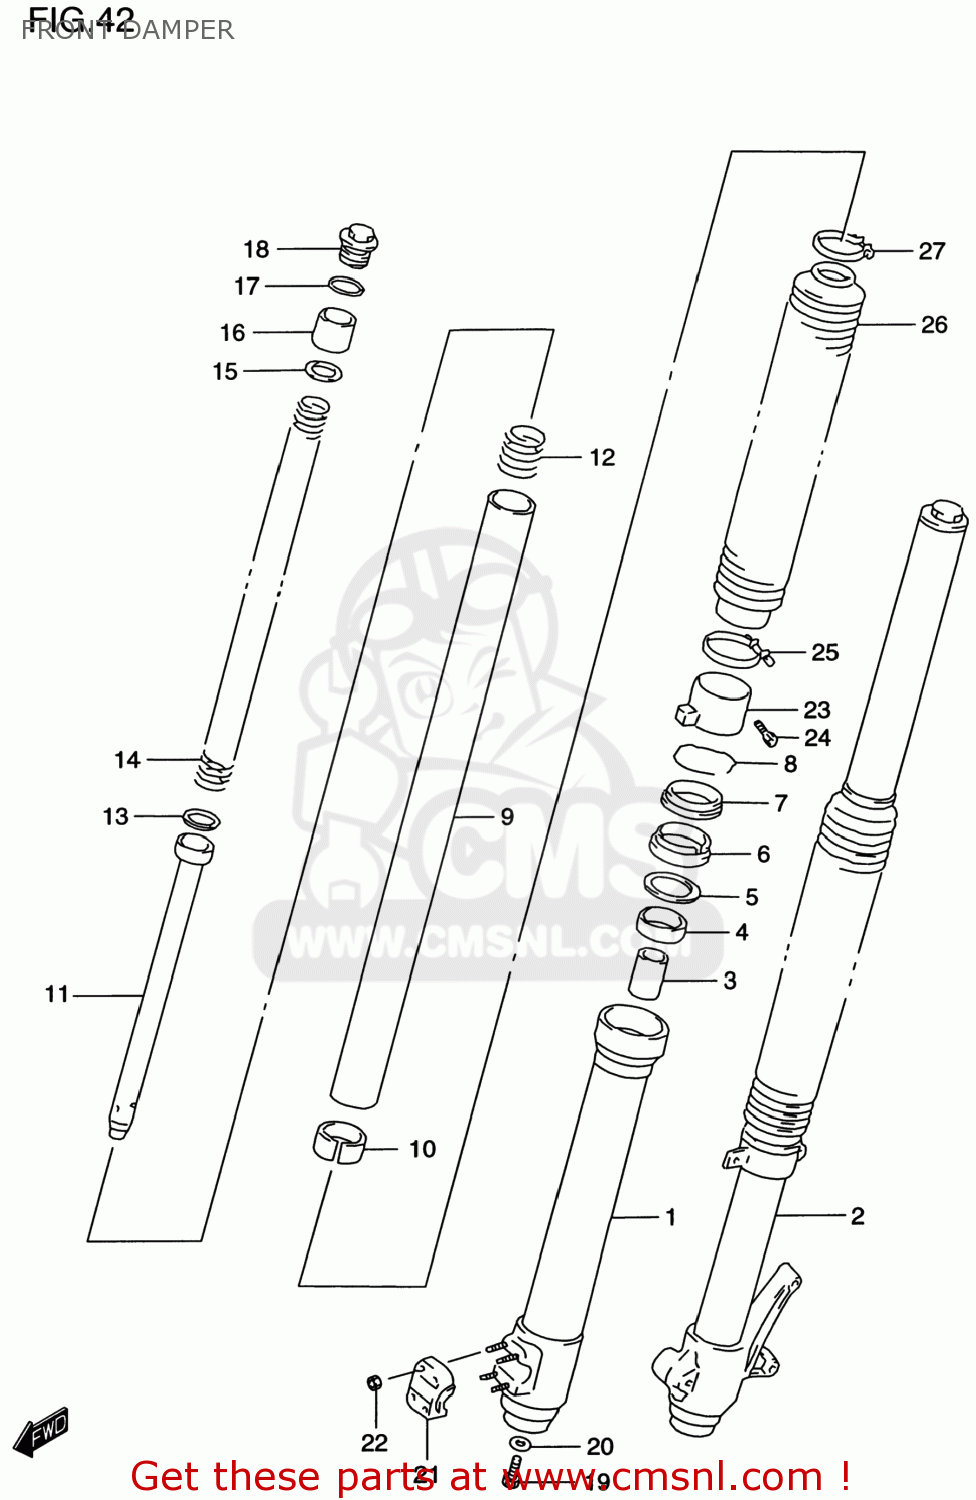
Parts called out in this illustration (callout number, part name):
1	TUBE,OUTER,R
2	TUBE,OUTER,L
3	PIECE,OIL LOCK
4	METAL,SLIDE
5	WASHER
6	SEAL,OIL
7	SEAL,DUST
8	RING,STOPPER
9	TUBE,INNER
10	PISTON
11	CYLINDER
12	SPRING,REBOUND
13	RING,PISTON
14	SPRING
15	WASHER
16	SPACER
17	O RING
18	CAP,FORK
19	BOLT,FORK CYLINDER(10X25)
20	GASKET (NAS)
21	HOLDER,AXLE,R
22	NUT
23	GUIDE,BOOT
24	BOLT
25	BAND,BOOT LWR
26	BOOT(GRAY)
27	BAND,BOOT
